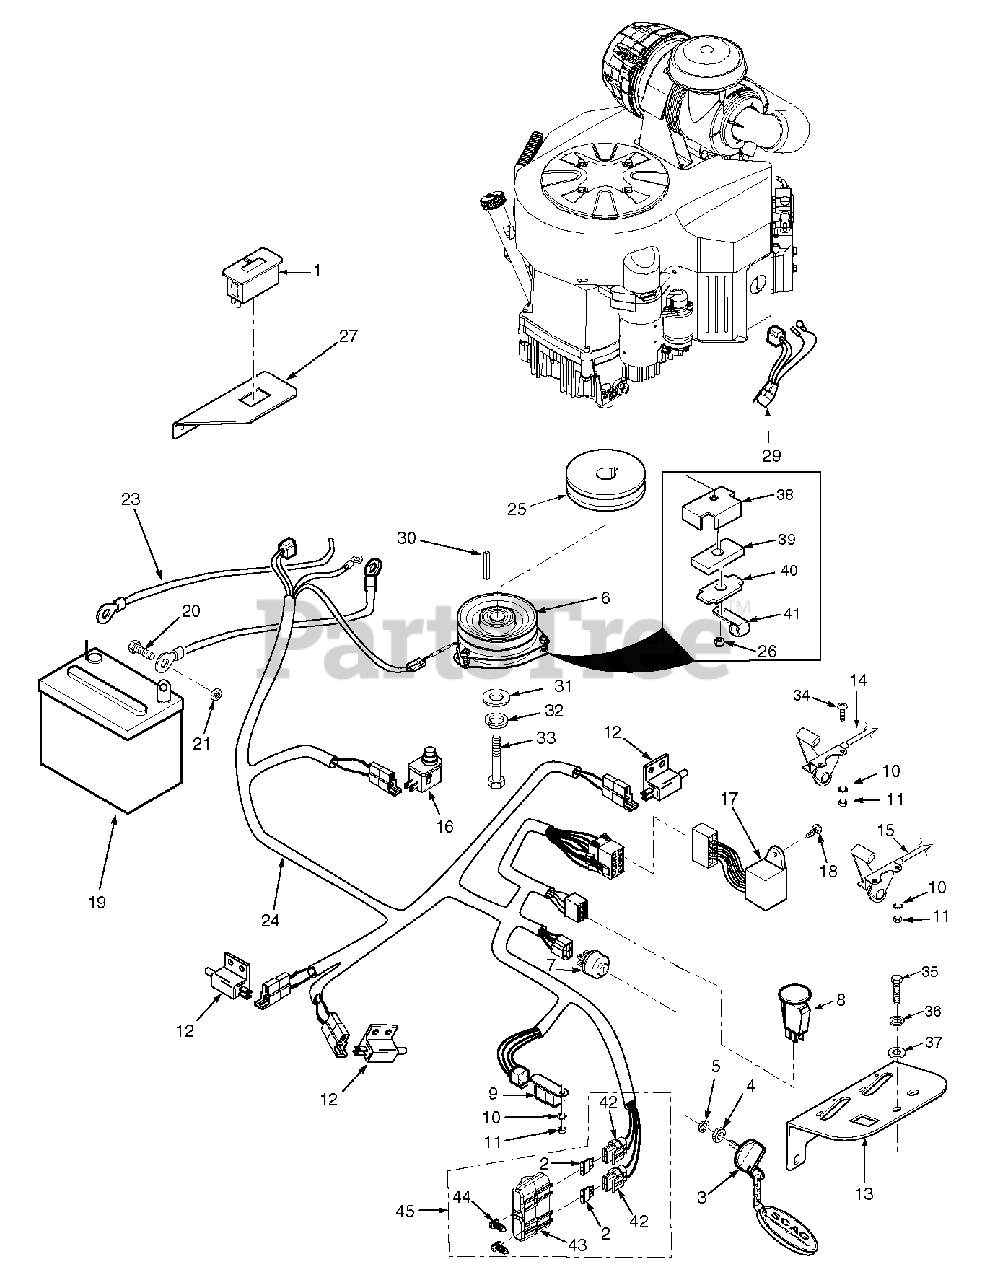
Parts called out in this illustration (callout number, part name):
1	Hourmeter
2	Fuse, 20 amp
3	Key, Ignition
3	Key Assembly w/Fob
4	Nut, Hex 5/8-32
5	Lockwasher, 5/8" Internal
6	Electric PTO Clutch GT3.5
7	Switch, Ignition
8	Switch, PTO
9	Relay
10	Lockwasher, #10 External Tooth
11	Nut, Hex #10-32
12	Switch, N/O
13	Panel, Instrument
14	Choke & Throttle Control - Kawasaki (Qty 2)
14	Choke Control - Kohler (Qty 1)
15	Throttle Control - Kohler (Qty 1)
16	Switch, Seat
17	Module, Interlock
18	Screw, #10-32 x .5" Phillips Head
19	Battery, 350CCA (Not Available Through Scag)
20	Bolt, Hex Head 1/4-20 x .5"
21	Nut, Hex 1/4-20
22	Cable, Battery Black (negative)
23	Cable, Battery Red (positive)
24	Wiring Harness, Main (Briggs & Stratton, Kohler)
24	Wire Harness, Main (Kawasaki)
25	Pulley, 5.45 OD x 1.125" Bore
26	Nut, Elastic Stop 5/16-18 Key
27	Mounting Bracket, Hour Meter
28	Screw, #10-32 x 1.5" Phillips Head
29	Adapter, Wiring Harness (Briggs & Stratton only)
29	Adapter, Wiring Harness (Kawasaki FX only)
29	Adapter, Wiring Harness (Kawasaki FS only)
29	Adapter, Wiring Harness (Kohler only)
30	Key, 1/4 x 1/4 x 3-1/4"
31	Flatwasher, 7/16-.469 x 1-3/4" x 1/4"
32	Lockwasher, 7/16"
33	Bolt, Hex Head 7/16-20 x 2-1/2" UNF
34	Screw, #10-32 x 3/4"
35	Bolt, Hex Head 5/16-18 x 3/4"
36	Lockwasher, 5/16"
37	Flatwasher, 5/16-.375 x .875 x .083
38	Backing Plate
39	Rubber Pad, Clutch Stop
40	Plate, Backing
42	Fuse Holder
43	Cover, Sealed Double
